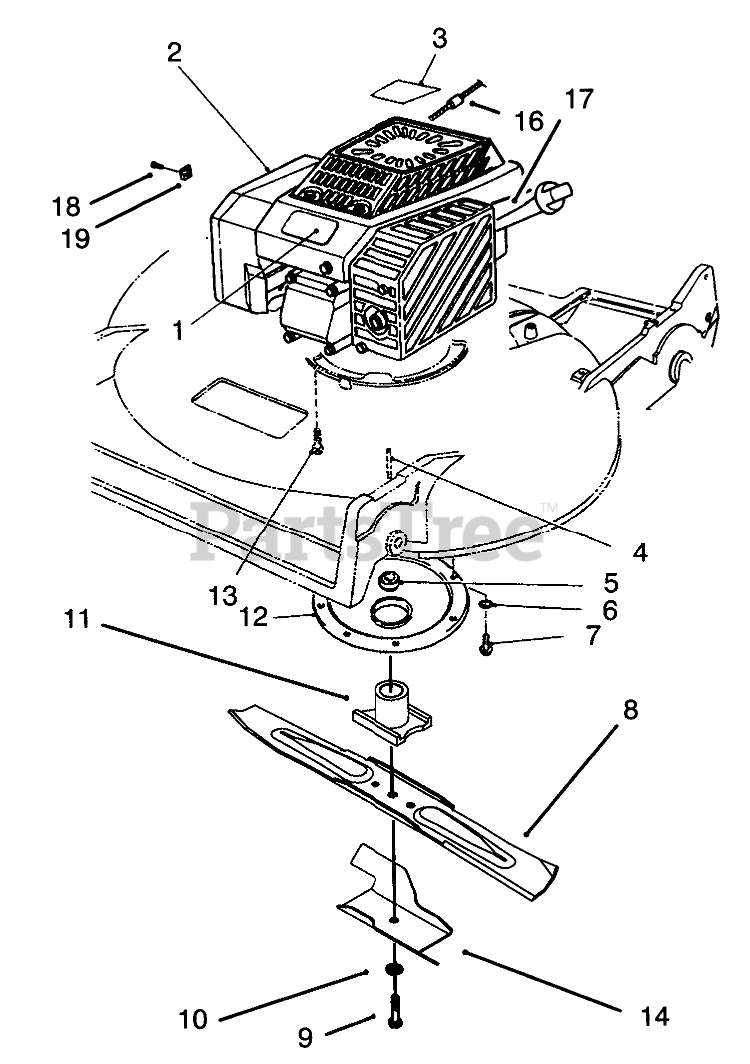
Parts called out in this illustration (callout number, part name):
1	DECAL - PROLINE
2	Engine-Complete
3	DECAL - ENGINE
4	KEY-SQUARE
5	SPACER-BLADE RETAINER
6	WASHER-LOCK, INTERNAL
7	SCREW-HWHTF
8	Blade
9	SCREW-BLADE
10	WASHER-LOCK
11	RETAINER-BLADE
12	PROTECTOR-CRANKSHAFT
13	SCREW-HWH
14	Accelerator
16	STOP-ROPE
17	COVER - BRAKE F/W
18	CLAMP SCREW F/W ENGINE
19	CLAMP-CASING
